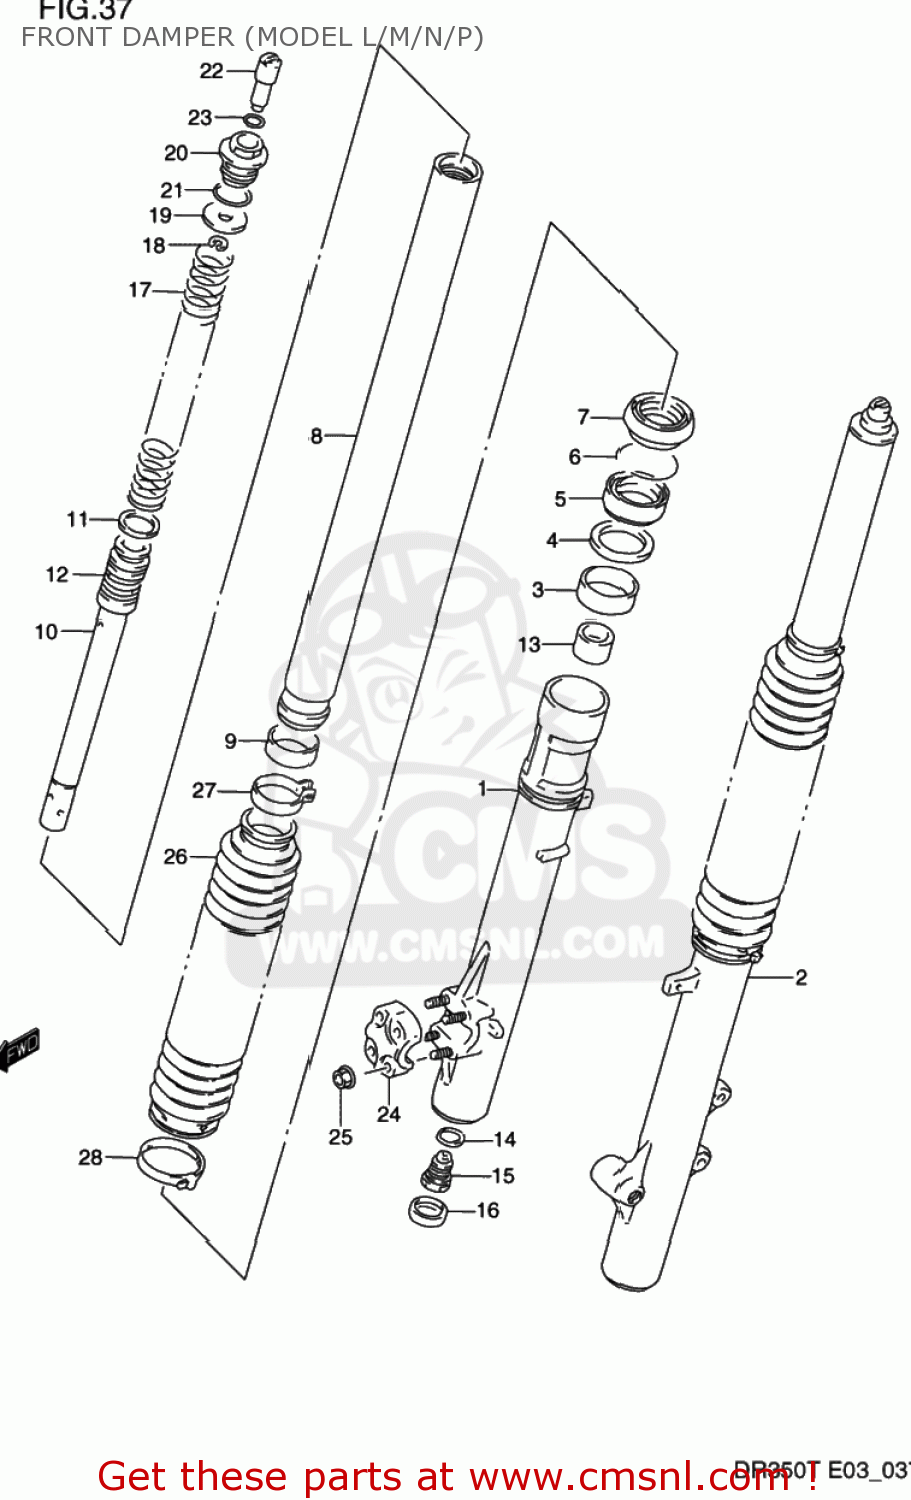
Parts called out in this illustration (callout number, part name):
1	TUBE,OUTER,R
2	TUBE,OUTER,L
3	BUSH,GUIDE
4	SPACER,SEAL
5	SEAL,OIL
6	CIRCLIP,FORK OIL SEAL
7	DUST SEAL
8	TUBE,INNER
9	BUSH,SLIDE
10	CYLINDER
11	RING,PISTON
12	SPRING,REBOUND
13	PIECE,OIL LOCK
14	GASKET (NAS)
15	BOLT,LWR
16	CAP,LOWER
17	SPRING,MAIN
18	E RING
19	SEAT,SPRING
20	BOLT,FORK
21	O RING
22	ADJUSTER,SPRING
23	O RING
24	HOLDER,AXLE
25	NUT,HOLDER
26	BOOT
27	BAND,BOOT UPR
28	BAND,BOOT LWR
